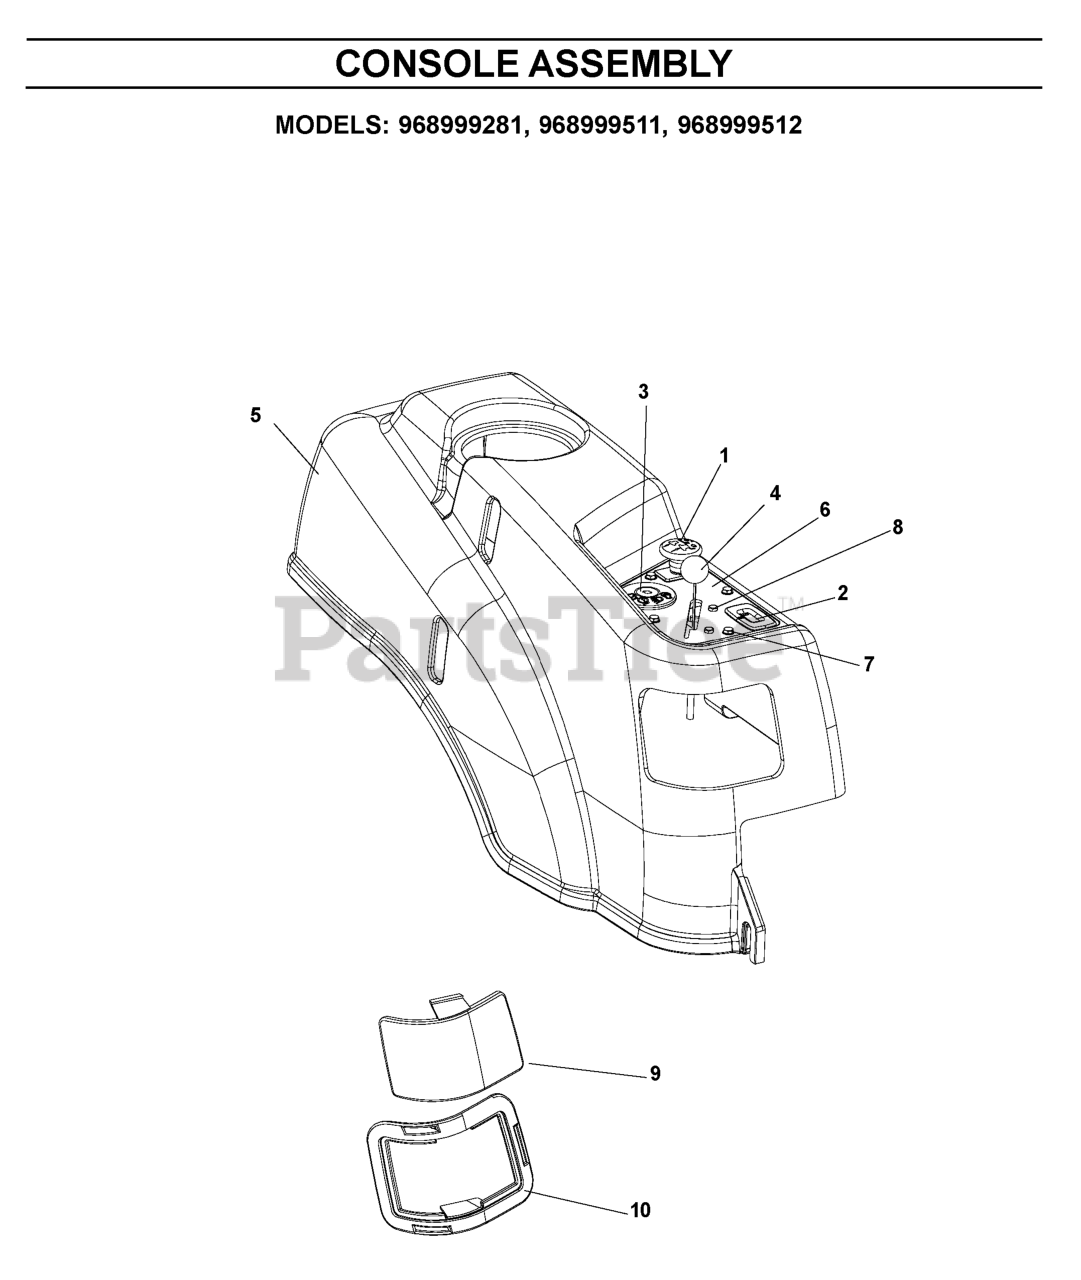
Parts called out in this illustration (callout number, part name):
1	RP.SWITCH, BLADE
2	HOUR METER
3	IGNITION SWITCH
4	THROTTLE CABLE DETENT
5	FENDER, CONSOLE
6	PLATE.CONTROL.CONSOLE.BLACK
7	SCR #10-12X3/4 HEX WAS HD ZD
8	HCS #10-24 X 1/2
9	LENS, COLORED LEFT
10	RT HEADLIGHT RIM GREY
